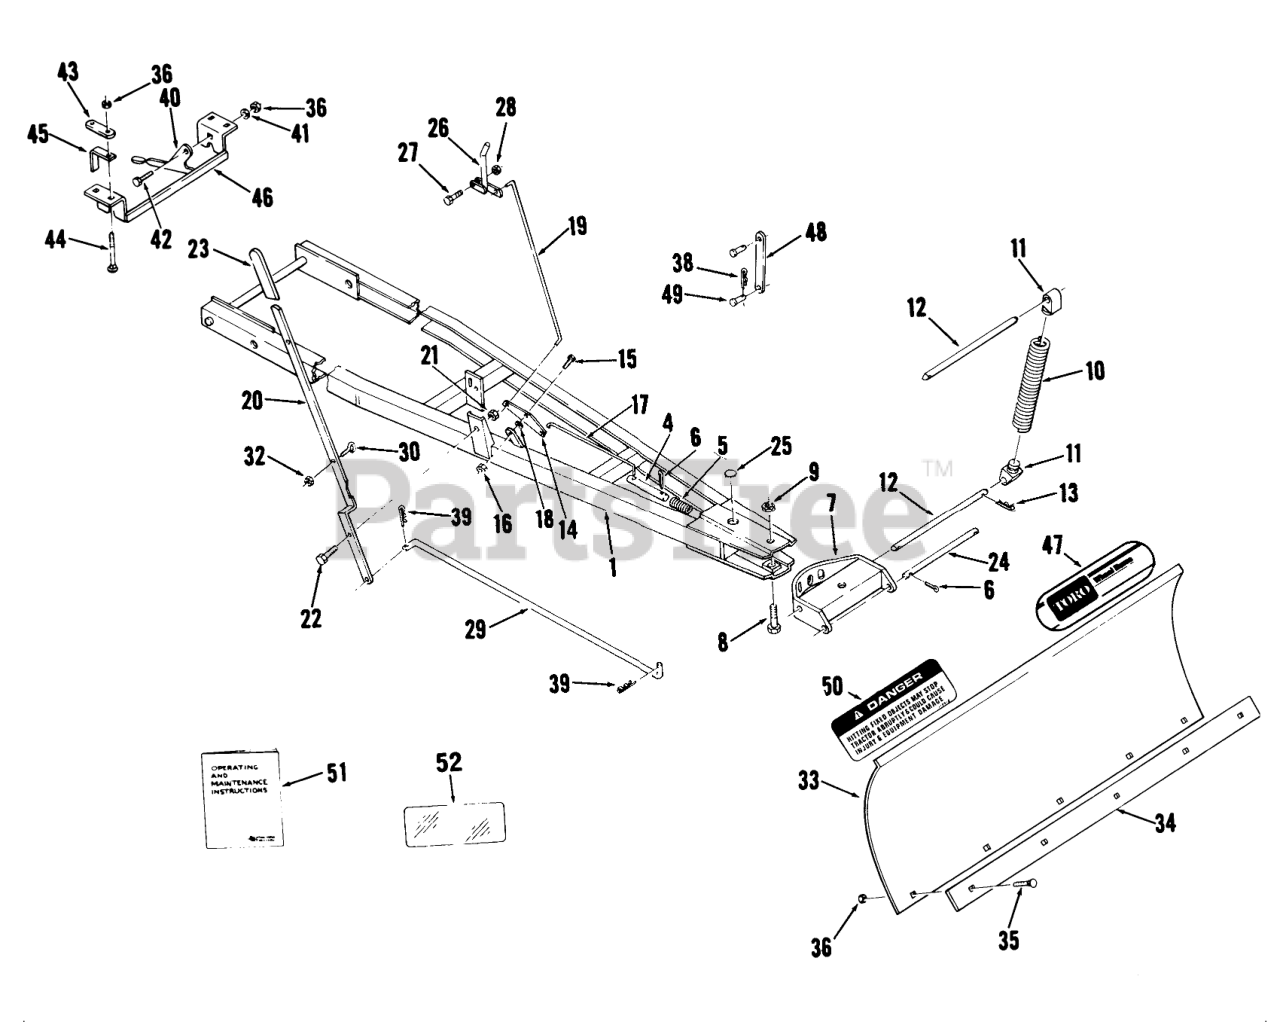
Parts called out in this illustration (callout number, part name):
1	Frame Assembly (Includes Reference #4, 5, 6)
4	Index Pin
5	SPRING-COMPRESSION
7	Sector and Channel
8	Bolt
9	Nut
10	Spring
11	Lug
12	ROD-PIVOT, BLADE
13	Hairpin
14	Index Plate
15	BOLT
16	NUT
17	Head-Cylinder
18	Washer
19	UPPER INDEX ROD
20	Index Lever
21	Jam Nut
22	Bolt
23	GRIP
24	ROD-LOWER
25	PLUG
26	INDEX LEVER
27	Bolt
28	Nut
30	EYEBOLT
32	Nut
33	Blade
34	Blade Edge Plate
35	Bolt-Carriage
36	NUT
38	Hairpin Cotter
39	Hairpin
40	PLATE-LATCHING
41	Washer
42	BOLT
43	BRACKET-REAR LINK MOUNTING
44	Bolt-Carriage
45	SPACER-BRACKET
46	Bracket
47	Decal
48	LINK-LIFT
49	Pin
50	DECAL-DANGER
51	Operating and Maintenance Instructions
52	DECAL-OVERLAY
